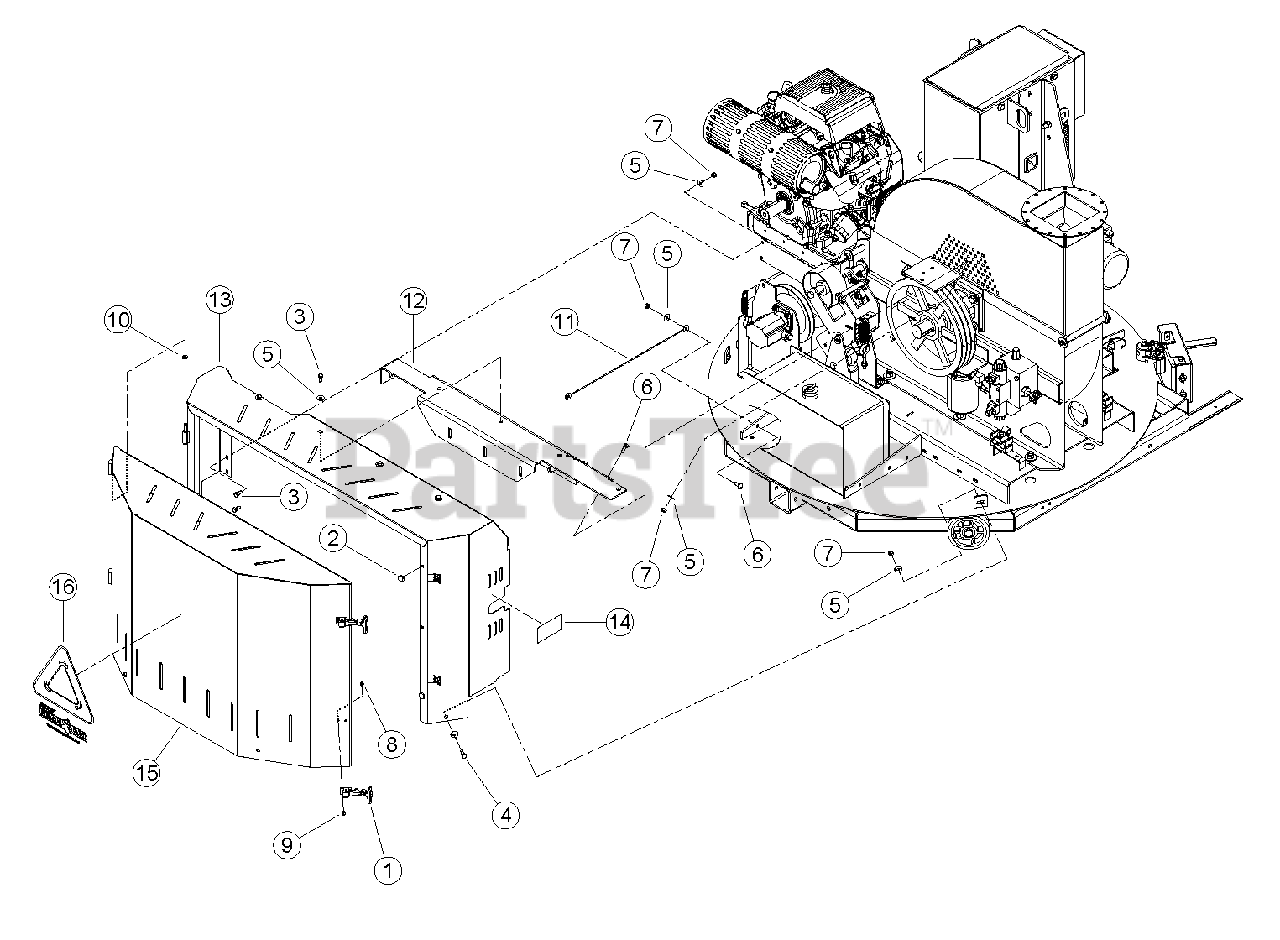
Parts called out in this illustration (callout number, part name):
1	LATCH, FLEXIBLE DRAW
2	BUMPER, RUBBER
3	BOLT, 5/16 X 3/4 HEX HD GR5 ZP
4	BOLT, 5/16 X 1 HHCS GR5 NC ZP
5	WASHER, 5/16 FLAT ZP
6	BOLT, 5/16 X 1 CRG GR5 ZP
7	NUT, 5/16 NE NYLOCK ZP
8	NUT, 10/24 NYLOCK TYPE NM ZP
9	SCREW, MCH 10-24 X 1/2 PAN HD,PH ZP
10	HINGE, BRASS RING
11	LANYARD, STEEL W/ PVC 1/8 X 20
12	WELDMENT, ENGINE TIE
13	ASSEMBLY, SHIELD REAR SERVICE PART
14	DECAL, FEED SPEED
15	ASSEMBLY, SHIELD FRONT SERVICE PART
16	DECAL, CHIP IT LARGE
